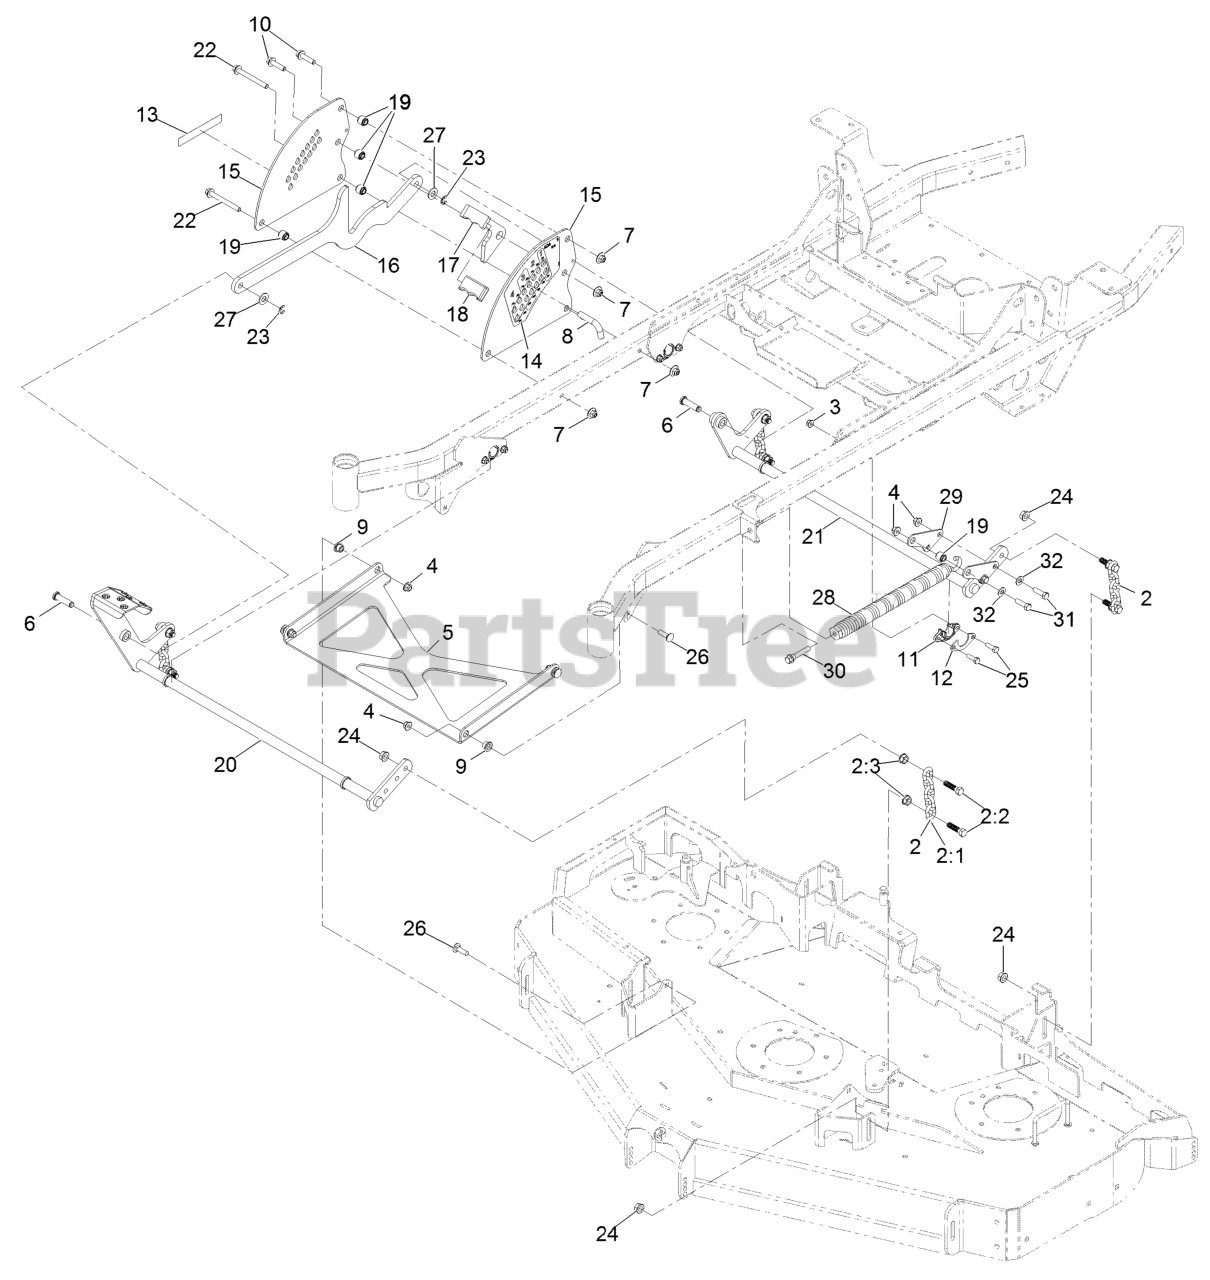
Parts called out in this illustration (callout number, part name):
2	DECK CHAIN ASM
2:1	CHAIN-LIFT, DECK
2:2	SCREW-HH
3	NUT-HF, NI
4	NUT-HF, NI
5	STRUT-DECK
6	PIN-CLEVIS
7	Nut-Nyloc 3/8-16 Flg
8	PIN-HOC
9	BUSHING-FLANGED
10	SCREW-HHF
11	BUSHING-FLANGE
12	GUSSET-LIFT, DECK
13	Decal-S-Series
14	DECAL-HEIGHT OF CUT
15	PLATE,DECK LIFT
17	TRANSPORT LOCK-HOC
18	GRIP-FLAT
19	SPACER-STEP, DOUBLE
20	WLD-DECK LIFT SHAFT FRT
21	WLD-DECK LIFT SHAFT RR
22	SCREW-HHF
23	RING-RETAINING, EXTERNAL
25	SCREW-HH
26	BOLT-CARR
27	WASHER-FLAT
28	SPRING-EXTENSION
29	BRACKET-SPRING ANCHOR REA
30	BOLT-SHOULDER
31	SCREW-HH
32	WASHER-FLAT
